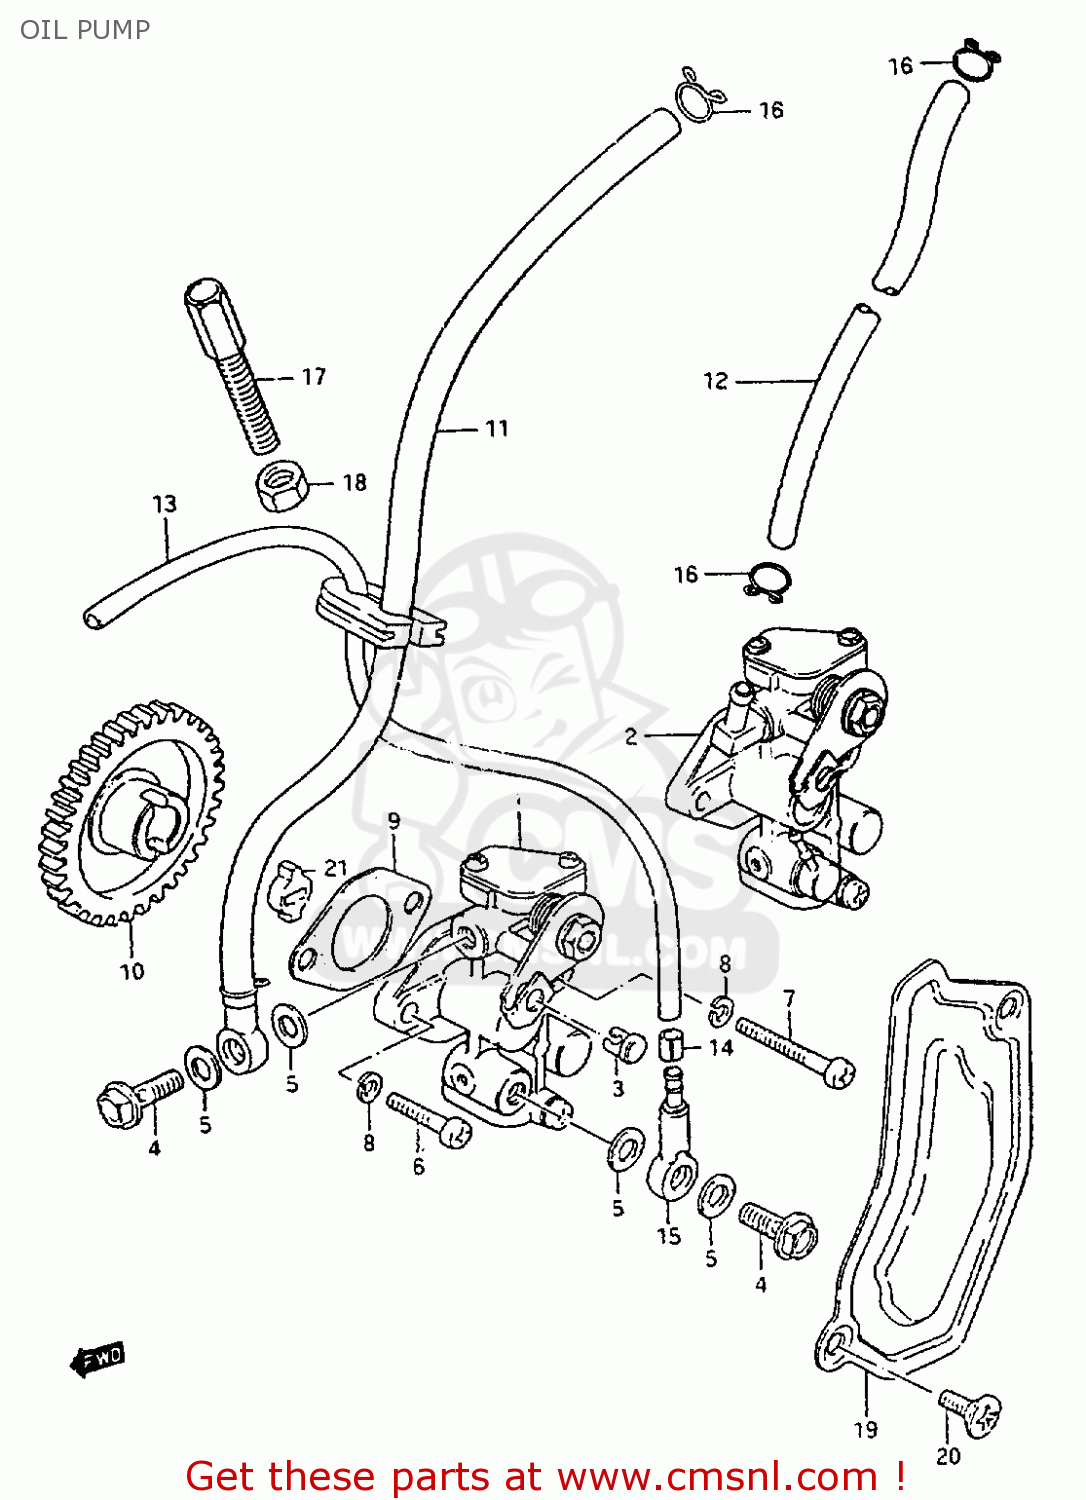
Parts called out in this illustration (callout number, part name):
1	PUMP ASSEMBLY,OIL
2	PUMP ASSY,OIL
3	TERMINAL,CABLE
4	UNION BOLT
5	GASKET(6.2X11X1).2 (NAS)
6	SCREW
7	SCREW
8	LOCK WASHER
9	GASKET,OIL PUMP (NAS)
10	GEAR,OIL PUMP DRIVE
11	HOSE, OIL INLET
12	HOSE
13	HOSE,OIL
14	CLIP
15	VALVE,CHECK
16	CLIP
17	BOLT
18	NUT
19	CAP,OIL PUMP INSPECTION
20	SCREW
21	PIECE,OIL PUMP DRIVE
